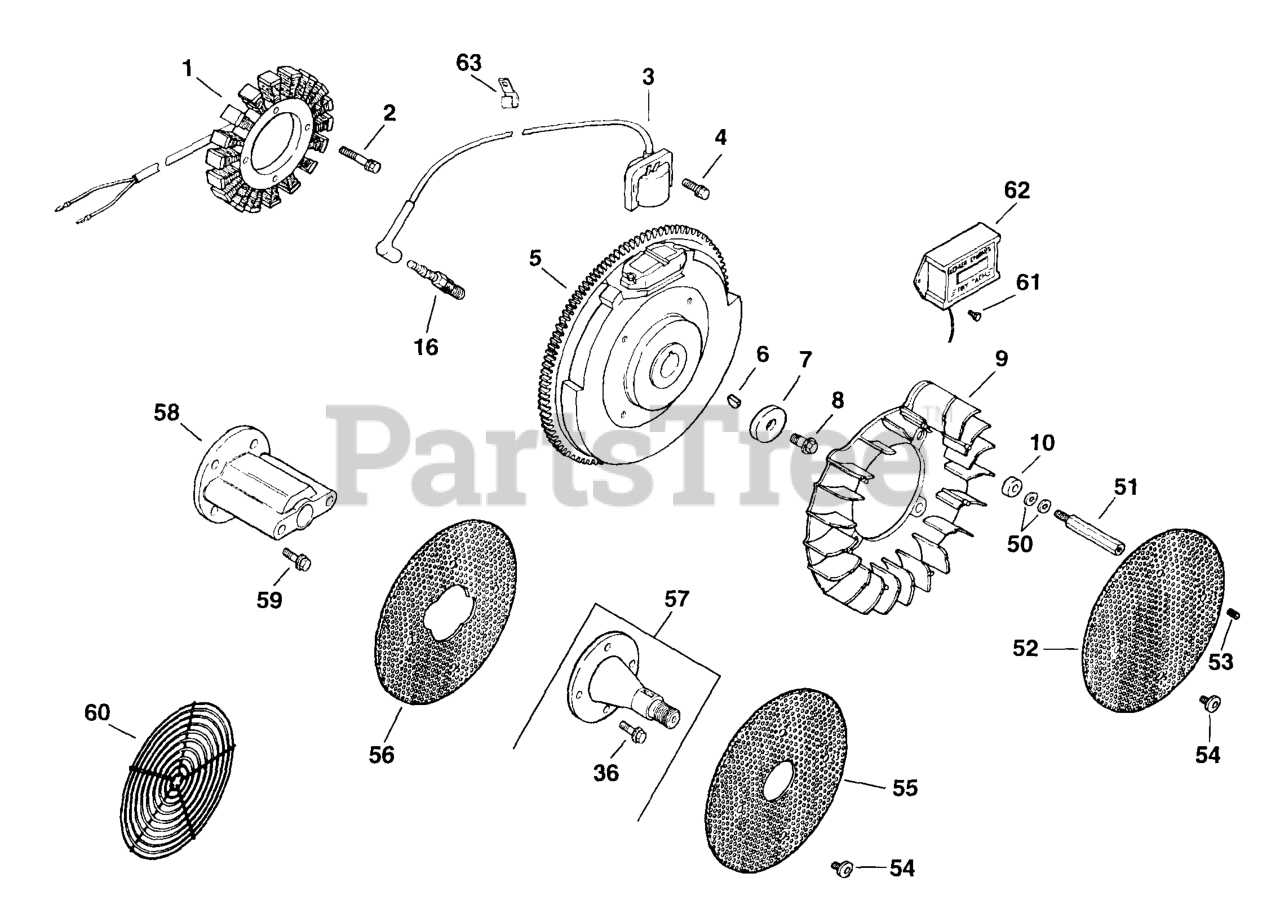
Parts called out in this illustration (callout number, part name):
1	Stator (15 Amp)
2	Screw, Hex. Cap M5x0.8x25
5	Flywheel
7	Washer, Plain 3/8"
8	Screw, Hex. Flange M10x1.5x76
10	Spacer, Fan
16	Spark Plug
36	Screw, Hex. Flange M8x1.25x25
50	Washer, Plain 1/4"
51	Stud, Grass Screen
53	Screw, Hex. Socket Hd. Set 10-24x1/4"
54	Screw, Truss Socket Hd. M6x1.0x10
55	Screen, Grass
57	Kit, Front Drive Shaft
